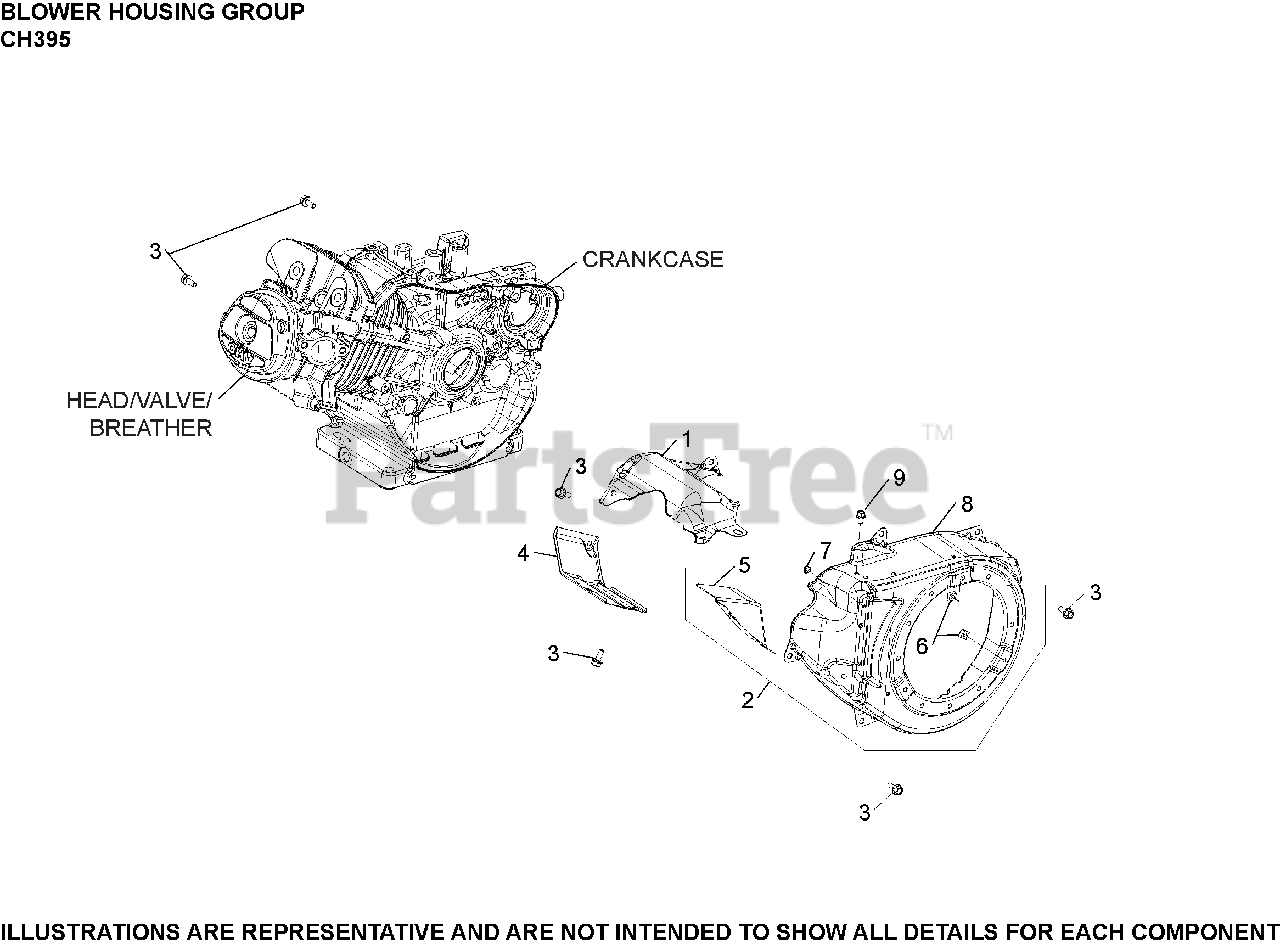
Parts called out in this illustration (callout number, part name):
1	SHIELD, UPPER HEAT
2	HOUSING, BLOWER ASSEMBLY
3	SCREW, HEX FLANGE (M6)-USE 25 086 433-S
4	SHIELD, CYLINDER HEAD
5	SHIELD, OUTSIDE CYLINDER HEAD
6	NUT, BLOWER HOUSING (CKY)
7	NUT, BLOWER HOUSING (CKY)
9	SCREW, M6 X 8 HEX FLANGE HEAD (CKY)
